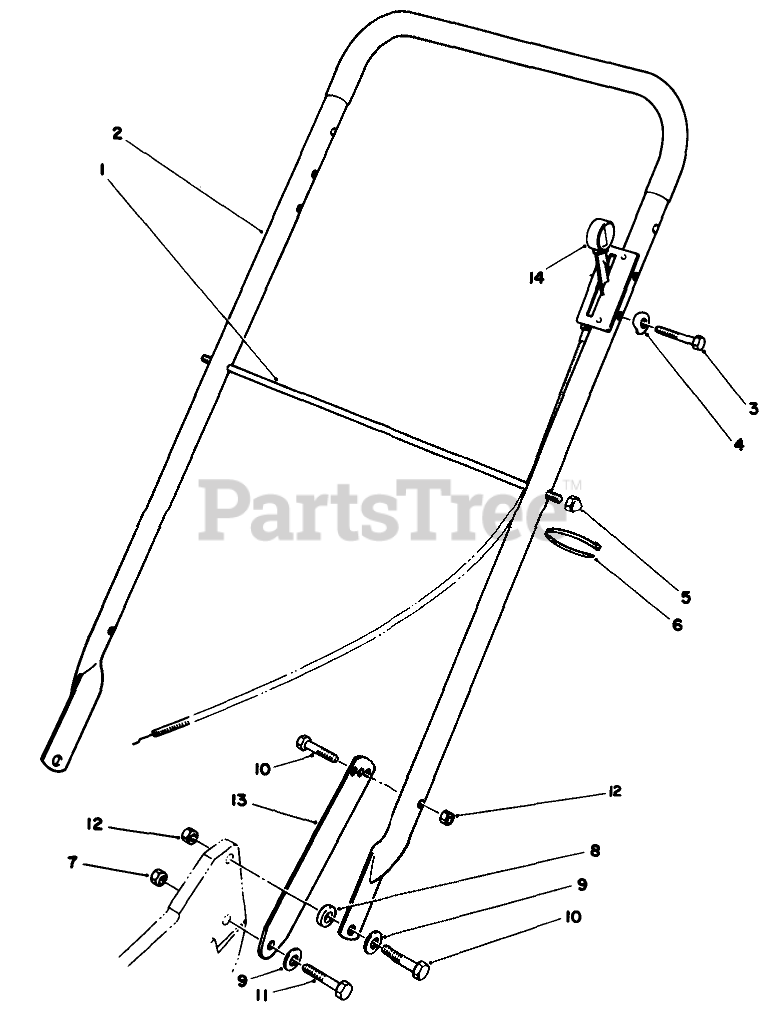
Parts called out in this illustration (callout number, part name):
1	ROD-SUPPORT, BAG
2	Handle
3	SCREW-HH
4	WASHER
5	NUT-CAP
6	TIE-CABLE
7	NUT-LOCK, NI
8	SPACER-PIN, MOUNTING
9	WASHER-BELLEVILLE
10	SCREW-HH
11	SCREW-HH
12	NUT-LOCK, NI
13	HANDLE LATCH
14	Control-Throttle Bend Type #1 Sheath Lg.49.5 Inch Wire Lg.2.8 Inch
